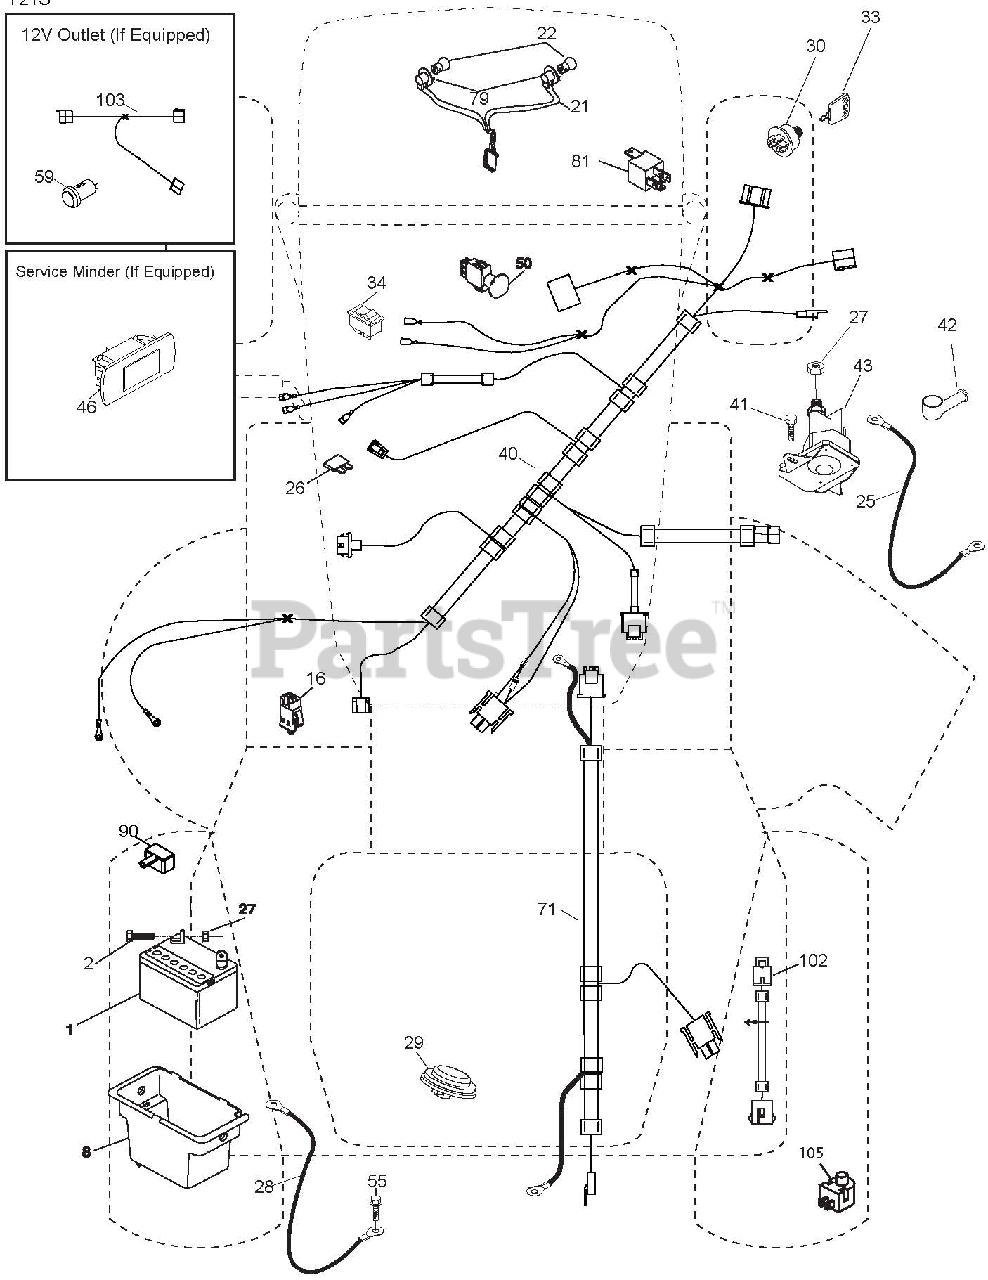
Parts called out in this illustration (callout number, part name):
1	BATTERY.12.VOLT.28.AMP.WET
2	BOLT.HEX.HD.1/4-20UNC X 3/4
8	BOX.BATTERY.MNT.REAR.LT.TEX.BL
16	SWITCH.INTERLOCK.NONO.GRAY
21	HARNESS ASM.LIGHT.22"(4152J)
22	BULB.LIGHT.#1156
25	CABLE.STARTER
26	FUSE.20 AMP.
27	Nut, Keps Hex 1/4-20 unc
28	CABLE.BLACK.22"REAR BATT.TEX
29	SWITCH.SEAT.DELTA.OPC.9LB.
30	SWITCH.IGN.DLTA.P-IN.ROS
33	KEY/CHAIN.BLISTER PACK.GEN.USA
34	SWITCH.LIGHT/RESET.B/B/RED.
40	HARNESS IGN. ELECTRIC RELAY
41	Screw 1/4-20 x 1/2
42	COVER.TERMINAL.RED
43	SOLENOID.W/BRASS PLUNGER.2005
46	GUAGE.SERVICE.MINDER
50	SWITCH.PTO.8 TERMINAL.BLACK
55	SCREW.5/16-18X3/4.SMGML.TAP/R
71	HARNESS.IGN
79	SOCKET ASM.BULB.TWISTLOCK
81	RELAY HARNESS SEALED
90	COVER TERMINAL BATTERY FR. TEX
102	HARNESS.PIGTAIL.K46.TEX.ROS
105	SWITCH.REVERSE.TT.PEDAL CONTRO
